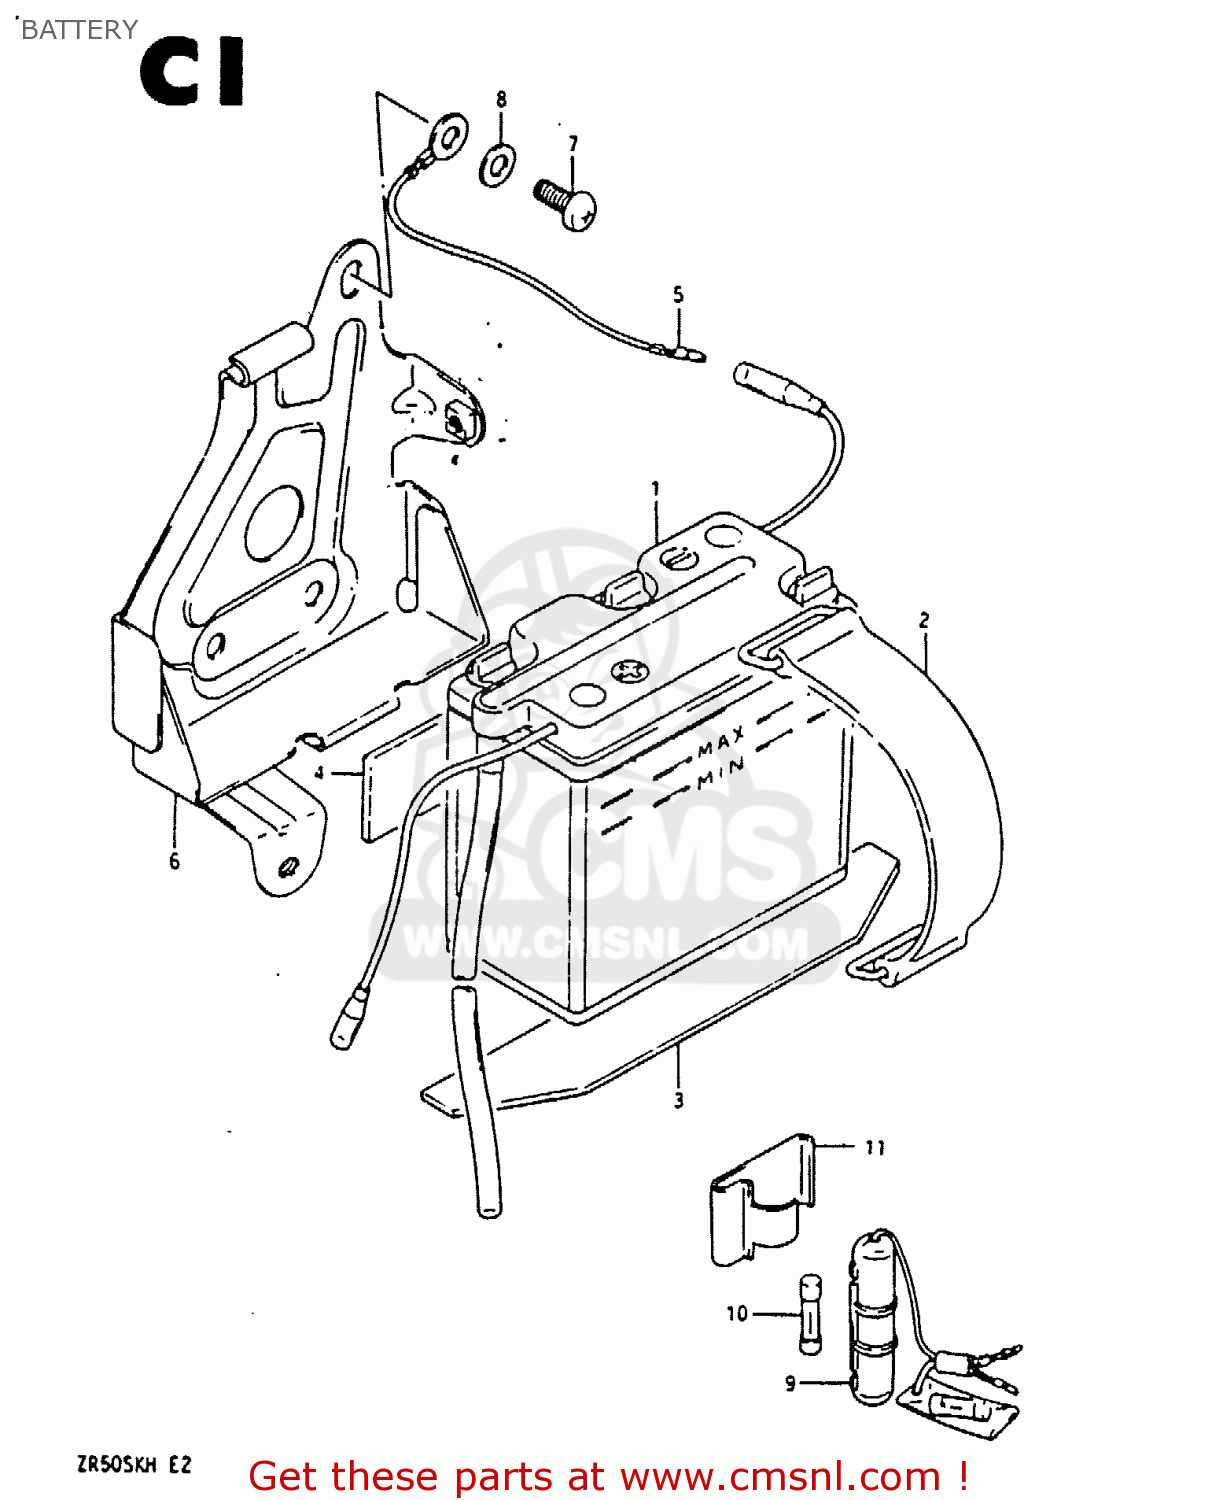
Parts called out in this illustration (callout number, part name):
1	BATTERY(6N4B-2A,6V4.2AH)
2	BAND
3	PROTECTOR,BATTERY
4	PROTECTOR(30X80X2)
5	LEAD WIRE
6	HOLDER, BATTERY
7	SCREW 6X12
8	WASHER
9	CASE ASSY,FUSE
10	FUSE(10A)
11	HOLDER,FUSE CASE
